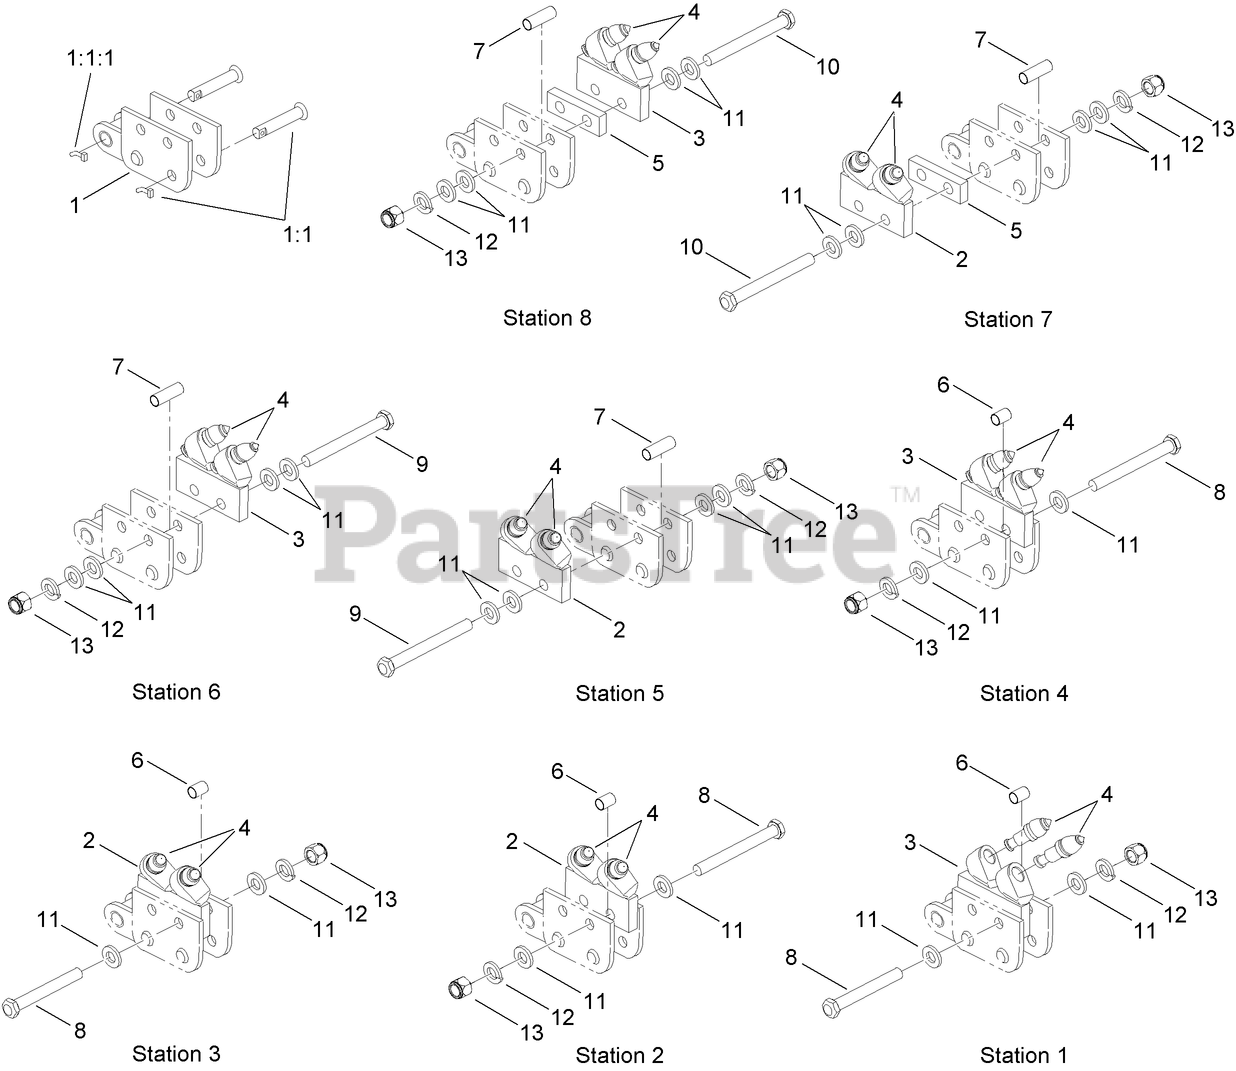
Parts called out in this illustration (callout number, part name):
1	CHAIN REPAIR LINK ASM
1:1	NOTCHED PIN AND KEEPER ASM
1:1:1	PIN-KEEPER
2	HOLDER-BIT, RH
3	HOLDER-BIT, LH
4	BIT-RETAINER, REAR
5	SPACER-FLAT
6	SPACER-TUBE, INSIDE ADAPTER
7	SPACER-TUBE, OUTSIDE MOUNT
8	BOLT-HH
9	BOLT-HH
10	BOLT-HH
11	WASHER-FLAT
12	WASHER-LOCK
13	NUT-LOCK
